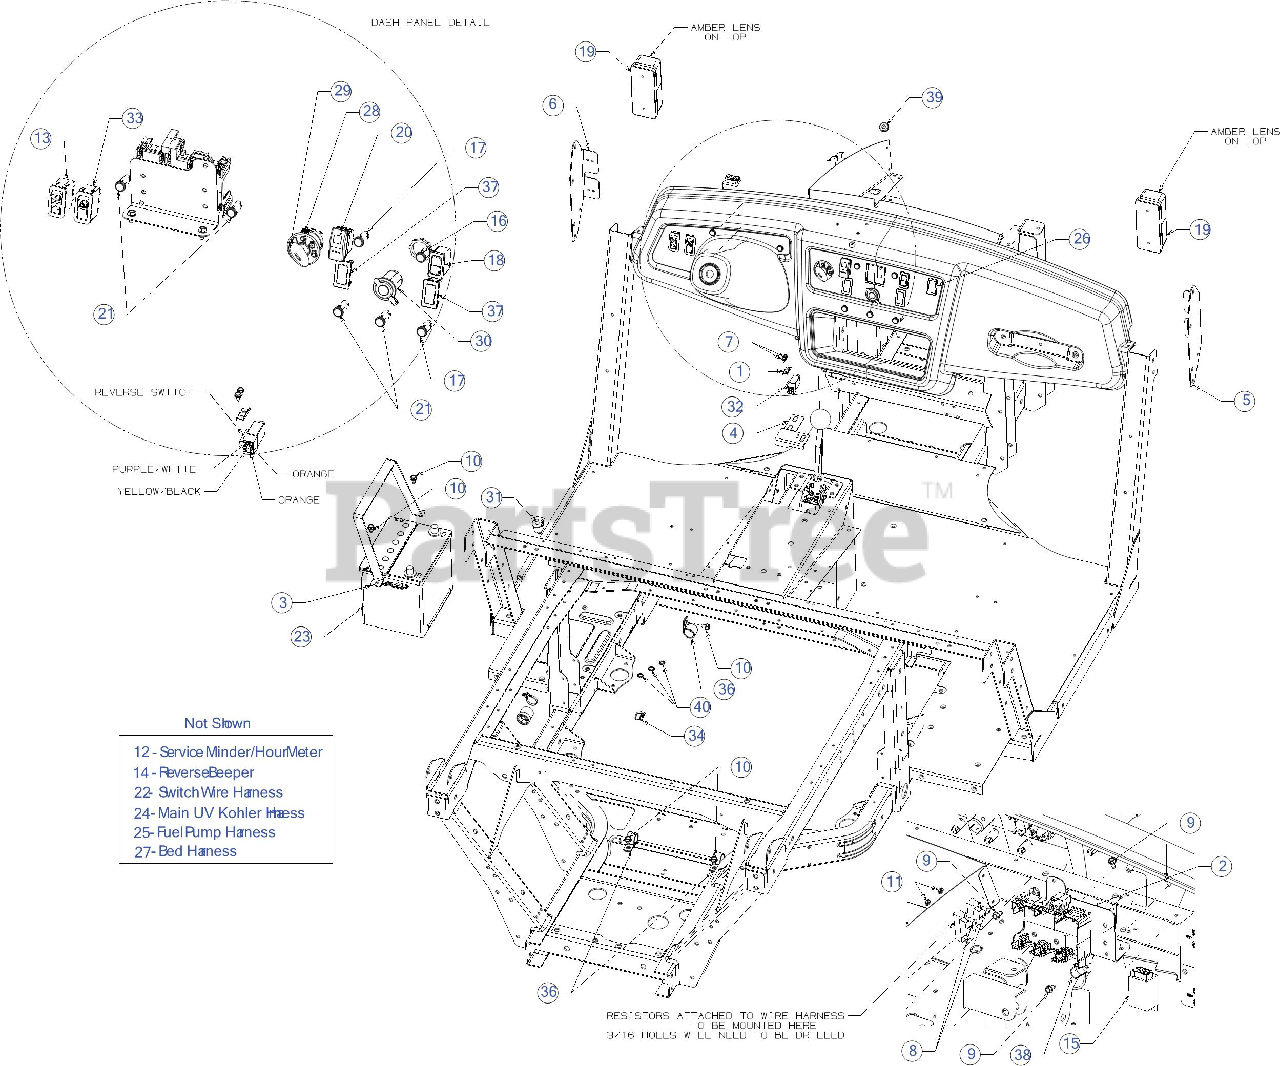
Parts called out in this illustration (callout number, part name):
1	PLATE-SWITCH
2	FUSE MOUNT BRACKET
3	BATTERY MOUNT BRACKET
4	SWITCH BRACKET
5	LIGHT BRACKET (LH)
6	LIGHT BRACKET (RH)
7	HEX SCREW AB-TAP #10-16 x 0.500
8	SCREW #10-24 x .500
9	SCREW 1/4-20 X.500
10	SCREW 5/16-18 x .500
11	LOCK NUT 10-24
13	DIRECTIONAL SWITCH
14	REVERSE BEEPER
15	TURN/HAZARD FLASHER
16	RED/REVERSE LIGHT
17	YELLOW/NEUTRAL LIGHT
18	4X4 ROCKER SWITCH
19	UV LAMP TURN
20	MASTER LIGHT SWITCH
21	GREEN INDICATOR LAMP
23	BATTERY-540 CCA
24	MAIN HARNESS
27	UV LIGHT HARNESS
28	IGNITION SWITCH
29	IGNITION KEY
30	POWER RECEPTICAL
31	SNAP MOUNT SWITCH
32	PLUNGER SWITCH
33	HAZARD LAMP SWITCH
36	HOSE CLAMP 1.0"
37	PANEL SWITCH PLUG
38	3 WAY RELAY HOLDER
